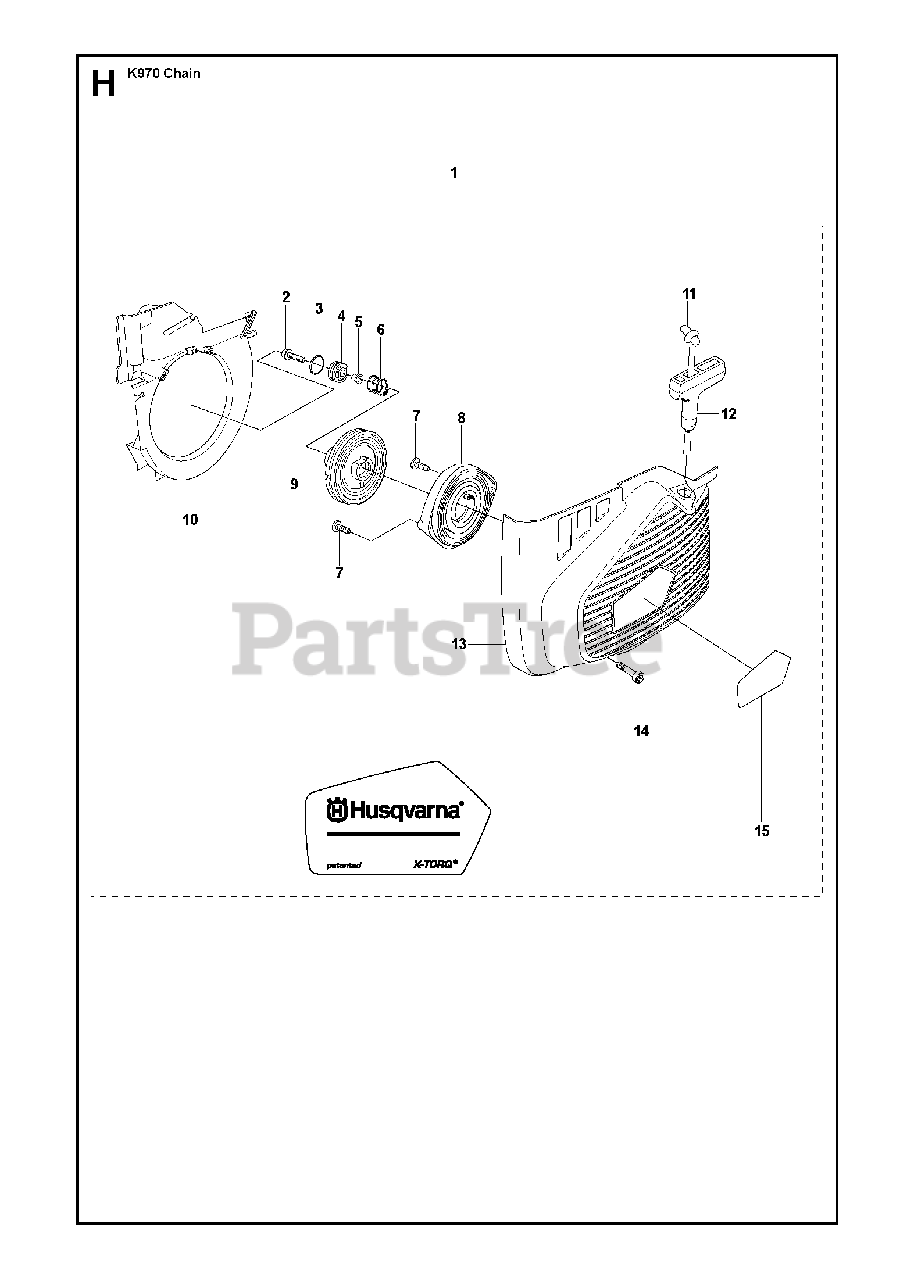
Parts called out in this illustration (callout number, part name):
1	STARTER ASSYIncl. 2 - 15
2	SCREW IHSCT
4	GROMMET
5	SPACING SLEEVE
6	COMPRESSION SPRING
7	SCREW CCRPANT
8	RECOIL SPRING
9	STARTER PULLEY
10	AIR CONDUCTOR
11	STARTER CORD50 m Coil
12	STARTER HANDLE
13	STARTER COVER
14	SCREW ITXSCM
